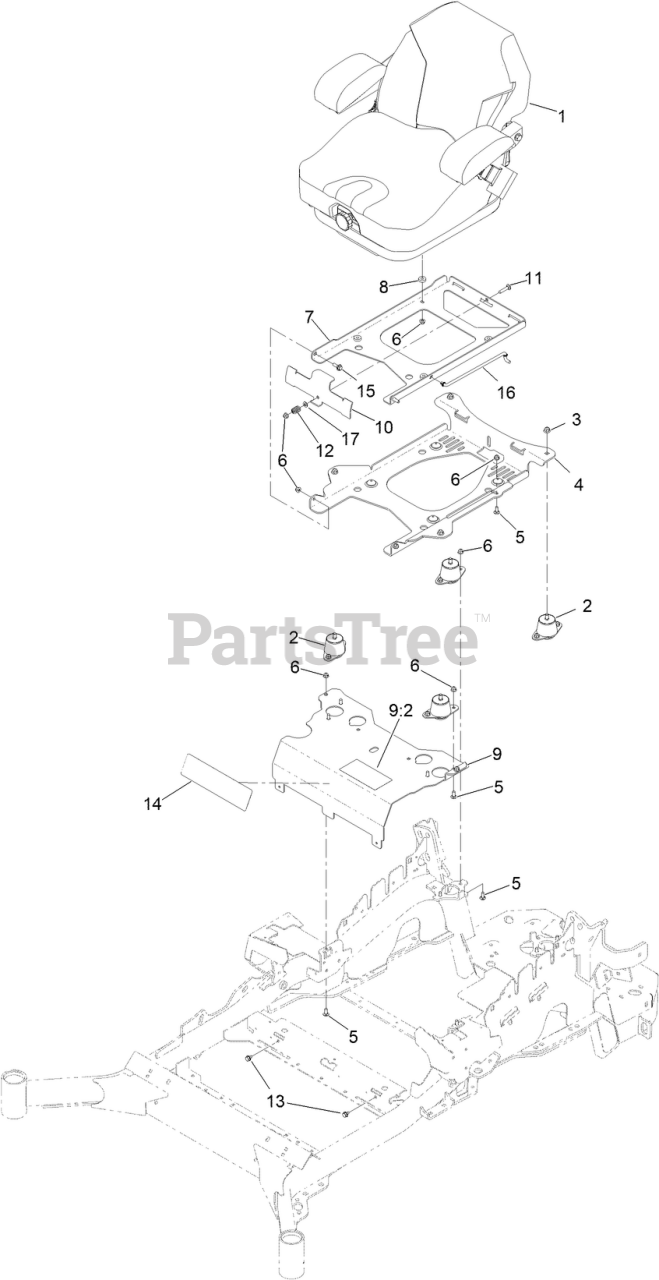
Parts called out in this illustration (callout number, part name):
1	SEAT-SUSPENSION
2	ISOLATOR-SEAT
3	NUT-HF, NI
4	PLATE-TILT, SEAT SUPPORT
5	SCREW-CARR
6	NUT-HF, NI
7	PLATE-FRAME, SEAT
9	MOUNT-SEAT W/DECALS
9:2	DECAL-LAZER 96 SERVICE AID
10	PLATE-LATCH, SEAT
11	BOLT-CARR
12	SPRING-COMPRESSION
13	SCREW
14	DECAL-CONSOLE
15	SCREW-SHOULDER
16	ROD-PROP
17	WASHER-PLAIN
